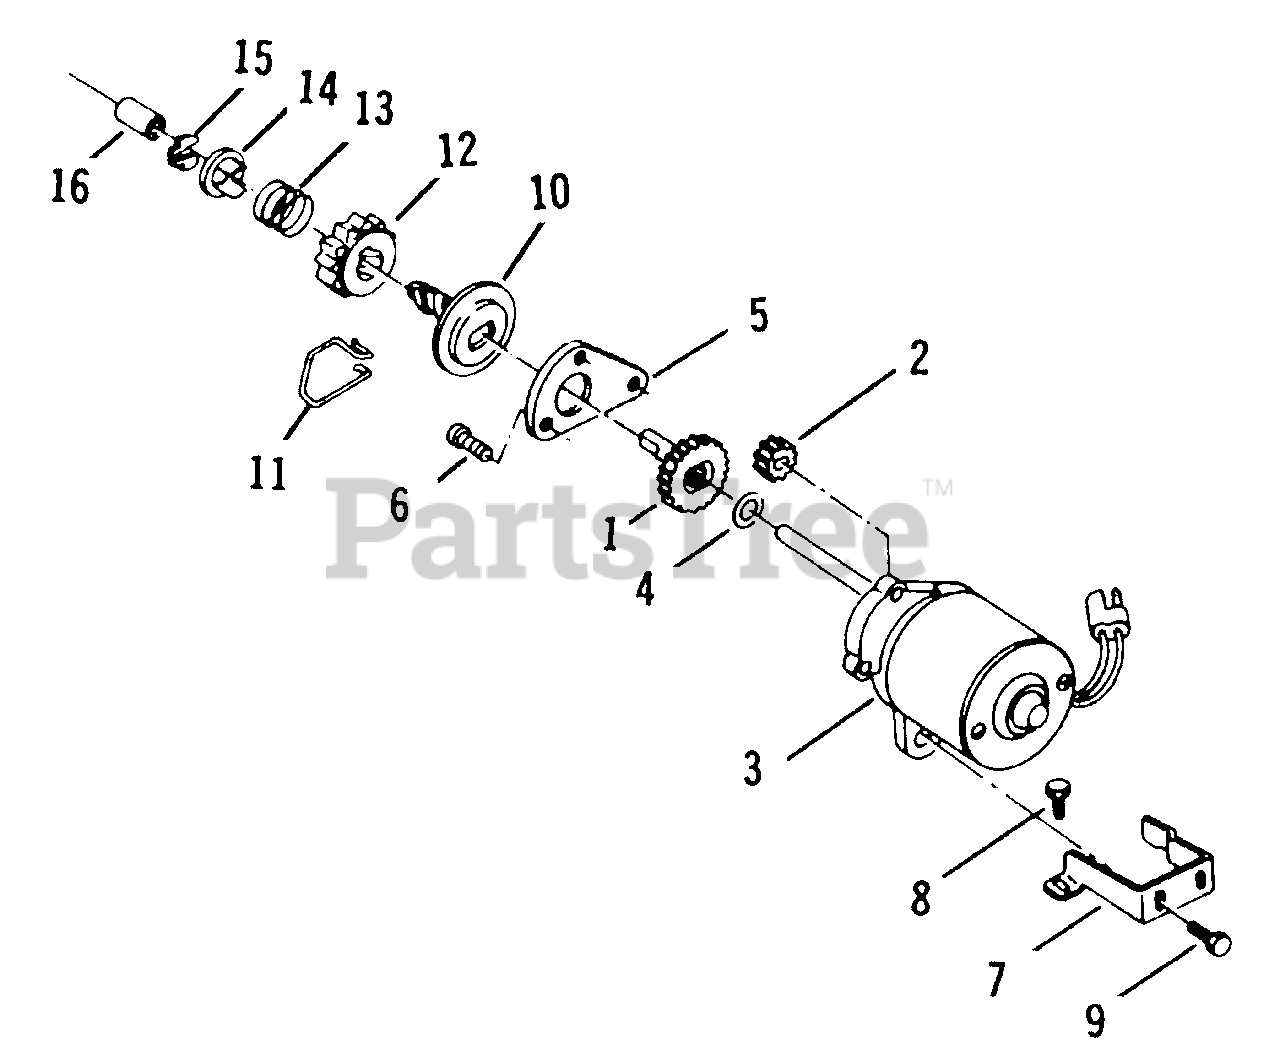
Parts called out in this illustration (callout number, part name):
1	Gear-Driven
2	Pinion-Motor Shaft
3	Motor Housing and Pin Ass'y.
4	Washer
5	Plate-Gear Cover
6	Screw
7	Bracket-Starter M tg.
8	Screw
9	Screw
10	Pinion, Spring and Clutch Ass'y.
11	Spring-Drag
12	Pinion
13	Spring-Pinion Return
14	Washer-Pinion Stop
15	Retaining Ring
16	Sleeve
